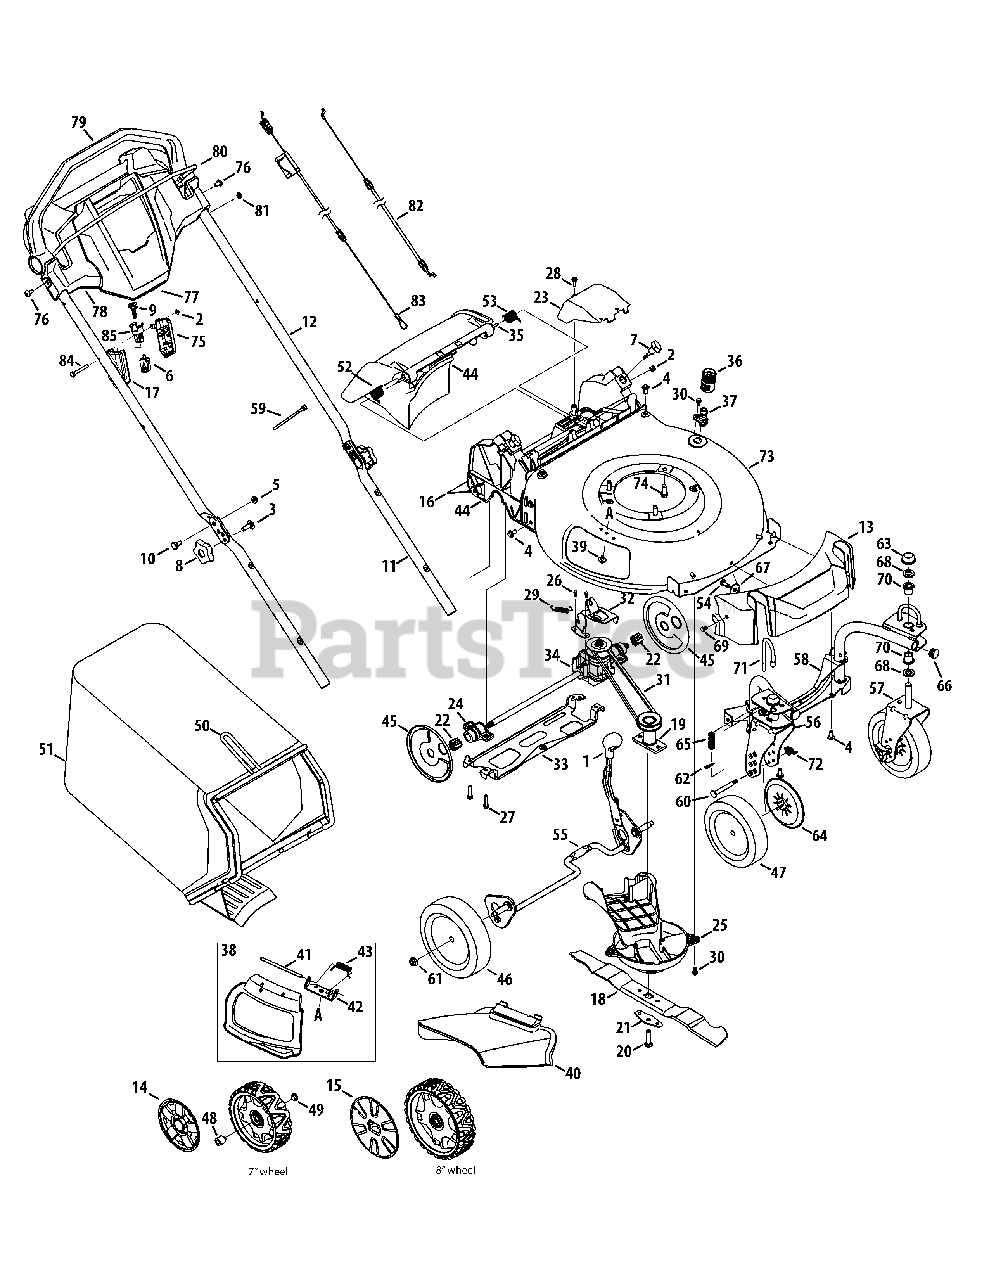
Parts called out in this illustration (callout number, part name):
1	Adjustment Knob
2	Nut, Sq., 1/4-20
3	Carriage Screw ,5/16-18
4	Screw, 5/16-14 x .750
5	Nut, Flange Lock, 1/4-20
6	Plunger Switch
10	Shdr. Screw, .375 x .126 x 1/4-20
11	Lower Handle
12	Upper Handle
13	Front Cover
14	Hubcap, 7"
15	Hubcap, 8"
16	Trail Shield
17	Electric Start Housing, RH
18	Mulching Blade
19	Blade Adapter
20	Screw, 3/8-24 x 1.50
21	Blade Bell Support
22	Spur Gear, 10T
23	Transmission Cover
24	Bearing Assembly
25	Engine Baffle
26	Screw, Hex Washer, .159 x .43
27	Screw, 1/4-15 x 1.25
28	Screw, 1/4-15 x .750
29	Exten. Spring, 2.405
30	Shoulder Screw, 1/4-20 x 0.50
32	Transmission Bracket
33	Rear Support Bracket
34	Transmission Assembly
36	Water Nozzle Adapter
37	Water Nozzle
38	Mulch Plug (Incl. 41-43)
40	Side Discharge Chute
42	Chute Deflector Bracket
43	Torsion Spring
44	Rear Discharge Door Assembly
45	Wheel Dust Cover
46	Rear Wheel, 8 x 2
47	Front Wheel, 7 x 2
48	Caster Hub, Long
49	Caster Hub, Short
50	Grass Catcher Frame
52	Torsion Spring - RH
53	Torsion Spring - LH
54	Self Tapping Screw, 5/16-18 x .750
55	Rear Axle Assembly
56	Caster Bracket Assembly, RH
57	Caster Bracket Assembly, LH
58	Caster Bracket Assembly
59	Cable Tie
60	Caster Axle, .374 Dia. x 2.59
61	Flange Lock Nut, 3/8-16
62	Cotter Pin, .072 Dia. x 1.13 Lg.
63	Push Cap, 5/8
64	Dust Cover, 7"
65	Compr. Sprng., .531 OD x 1.75 Lg
67	Washer, Flat, .330 x 1.25 x .06
68	Flat Washer, .640 x 1.12 x .125
69	Shdr. Screw, .50 x 1/4-20
70	Flange Bearing, .631 ID
71	Lock Pin: Front Wheel
72	Wing Nut, 1/4-20 w/Bell Washer
73	21" Deck
73	21" Deck (TSC)
74	Screw, tt, 3/8-16 x 1.00
75	Electric Start Housing, LH
76	Screw, 1/4-14 x .625
77	Trim Console
78	Handle Console
79	Drive Handle
81	Shoulder Spacer, .18 x .315 x .09
82	Control Cable
83	Drive Cable
84	Screw, 1/4-20 x 1.75
